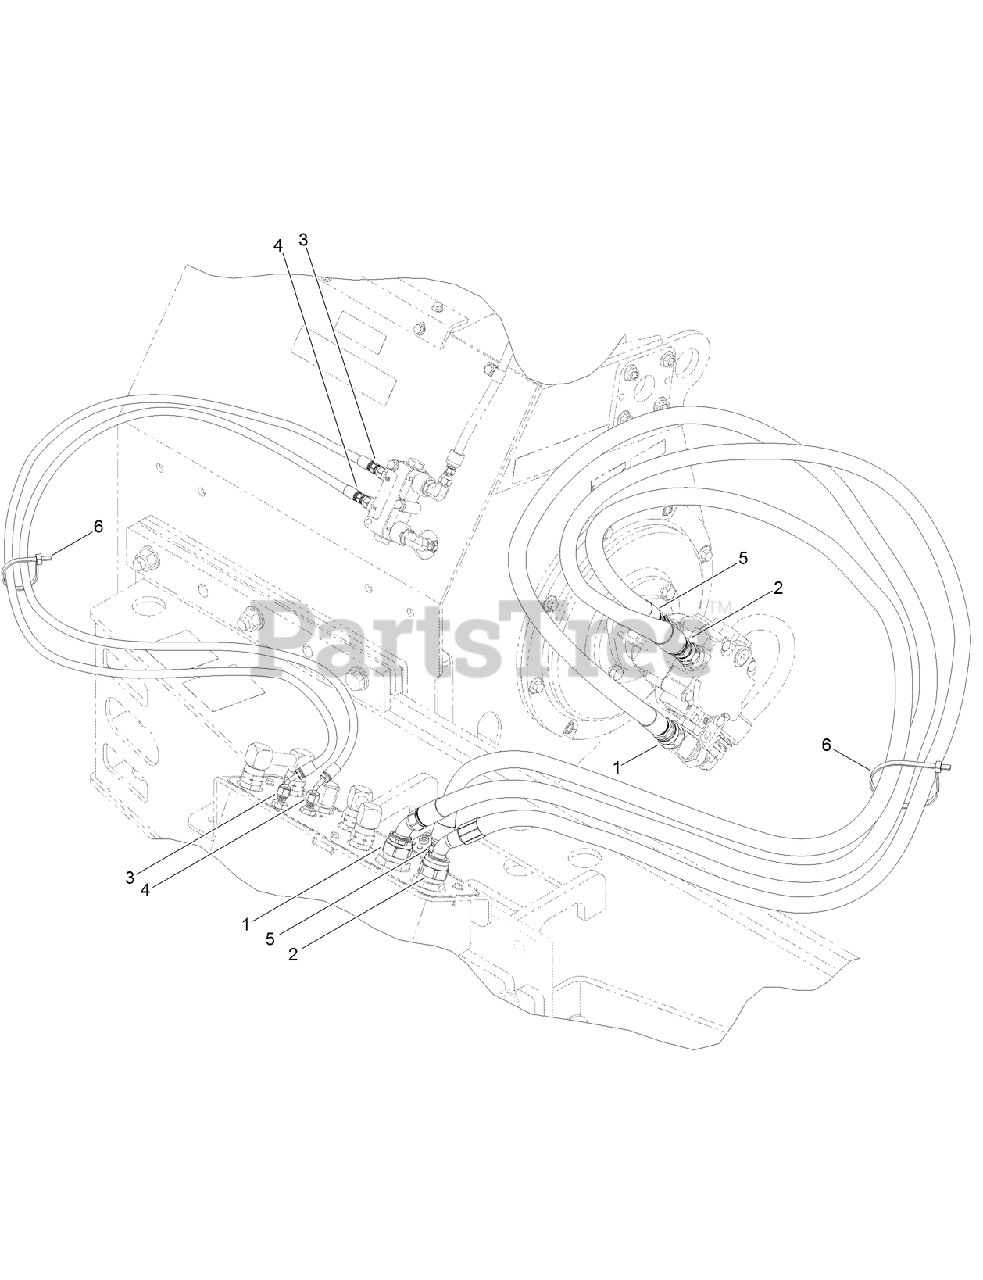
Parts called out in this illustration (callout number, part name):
1	HOSE-HYD
2	HOSE-HYD
3	HOSE-HYD
4	HOSE-HYD
5	HOSE-HYD
6	TIE-CABLE
